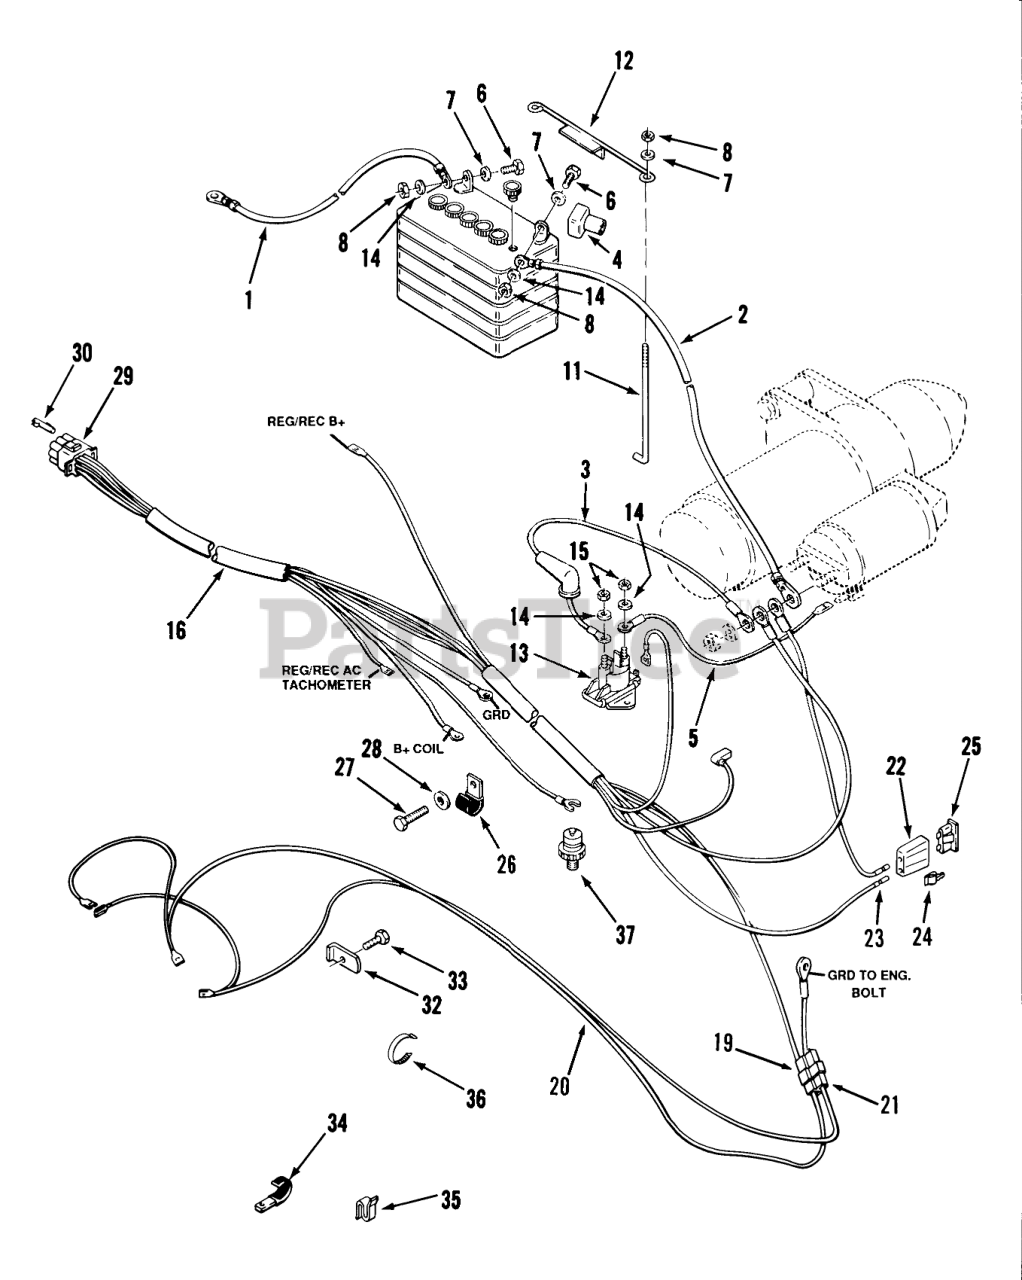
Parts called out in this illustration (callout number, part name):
1	ASS'Y-WIRE
2	SHIELD-SD DISCHARGE
3	ASS'Y-WIRE
4	Boot
5	ASS'Y-WIRE
6	Bolt
8	Nut
11	HOOK-BATTERY RETAIN
12	HOLDDOWN-BATTERY
13	SOLENOID-STARTER
14	Washer
15	Nut
16	Engine Wiring Harness
19	MALE CONNECTOR
20	HARNESS-HEADLIGHT
21	CONNECTOR BODY
22	AUTO-FUSEBLOCK TERM
23	TERMINAL FUSE
24	CLIP
25	FUSE-30 AMP
26	Clip
27	Bolt
28	LOCKWASHER 1/4 IT
29	CONNECTOR CAP
30	CONTACT SOCKET
32	LOCK-HEADLIGHT
33	Bolt
34	CLIP
35	SPEED CLIP
36	PLASTIC TIE
37	LOW OIL PRESSURE
